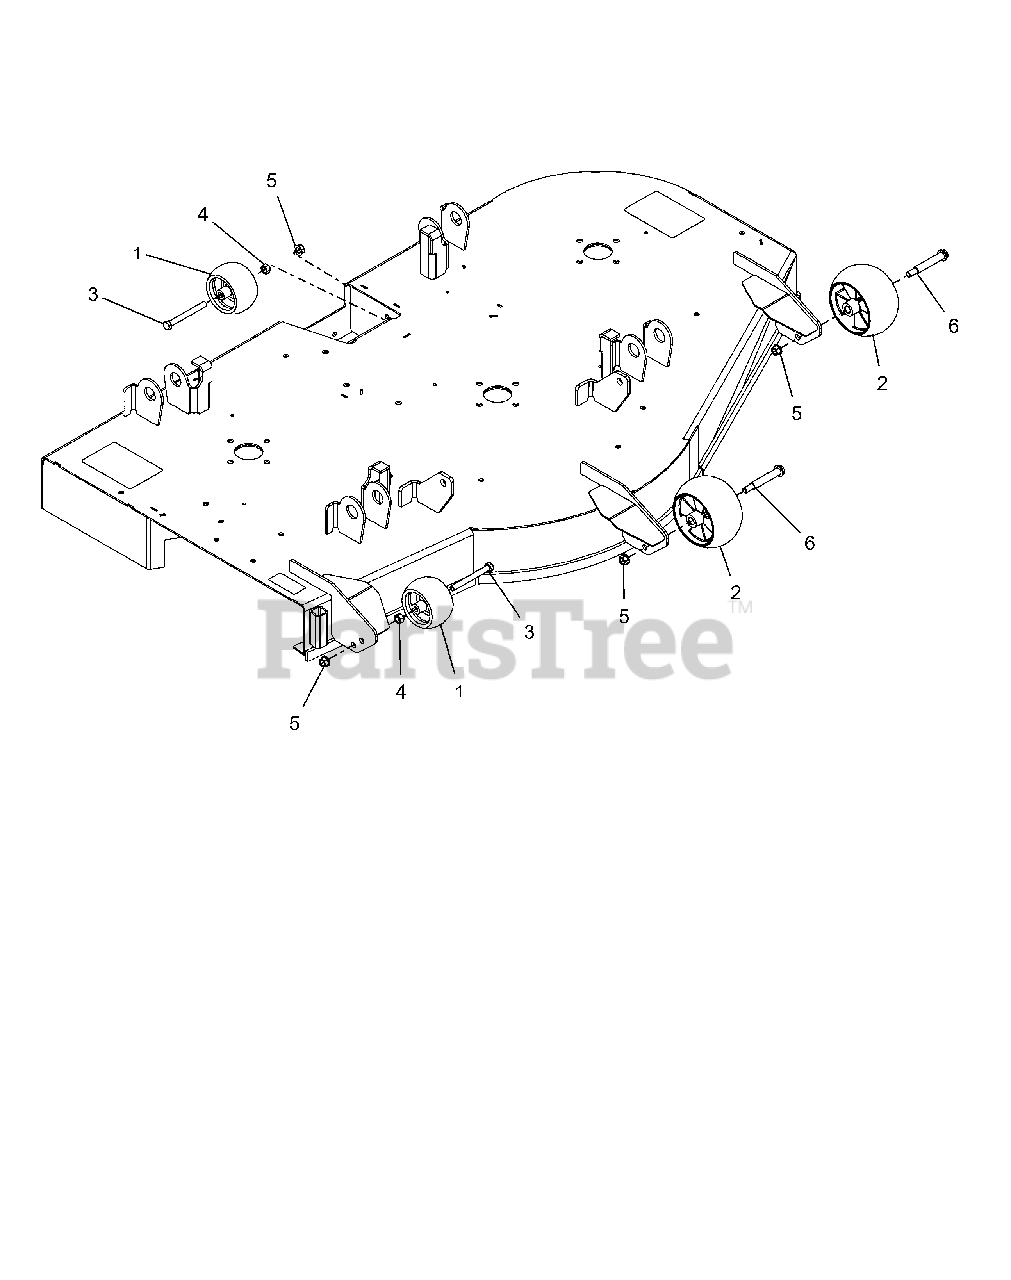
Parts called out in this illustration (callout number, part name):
2	ANTI-SCALP WHEEL - 5X OS
3	@BLT-HEX .38-16X3.50 GR5 YWZC
4	@NUT-HEX .38-16 YWZC
5	@NUT-LK-TOP-FLG .38-16 YWZC
6	BLT-SHLDR .38-16X2.50 HWH G5
